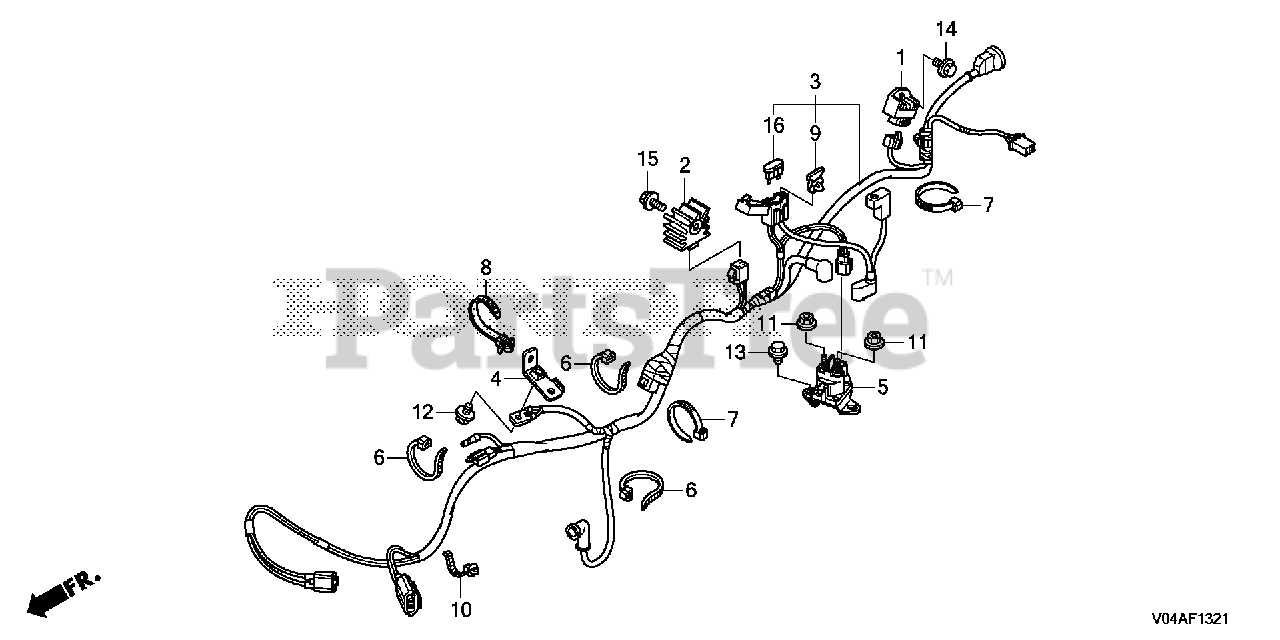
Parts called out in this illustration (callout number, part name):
2	RECTIFIER, REGULATOR (5A)
3	WIRE HARNESS ASSY., MAIN
4	BRACKET, WIRE HARNESS CLIP
5	SWITCH ASSY., STARTER MAGNETIC
6	BAND, WIRE (95MM)
7	BAND, WIRE (165MM) (BLACK)
8	STRAP, CABLE (118MM) *NH1L* (Honda Code 1170653). (BLACK)
9	CLIP, CONNECTOR (BEIGE)
10	CLIP, HARNESS BAND (145MM) (BLACK)
11	NUT, FLANGE (6MM)
12	BOLT, FLANGE (6X10)
13	BOLT, FLANGE (6X10)
14	BOLT, FLANGE (6X12) Use up to Engine SN 1543277.
15	BOLT, FLANGE (6X30)
16	FUSE, MINI (5A)
